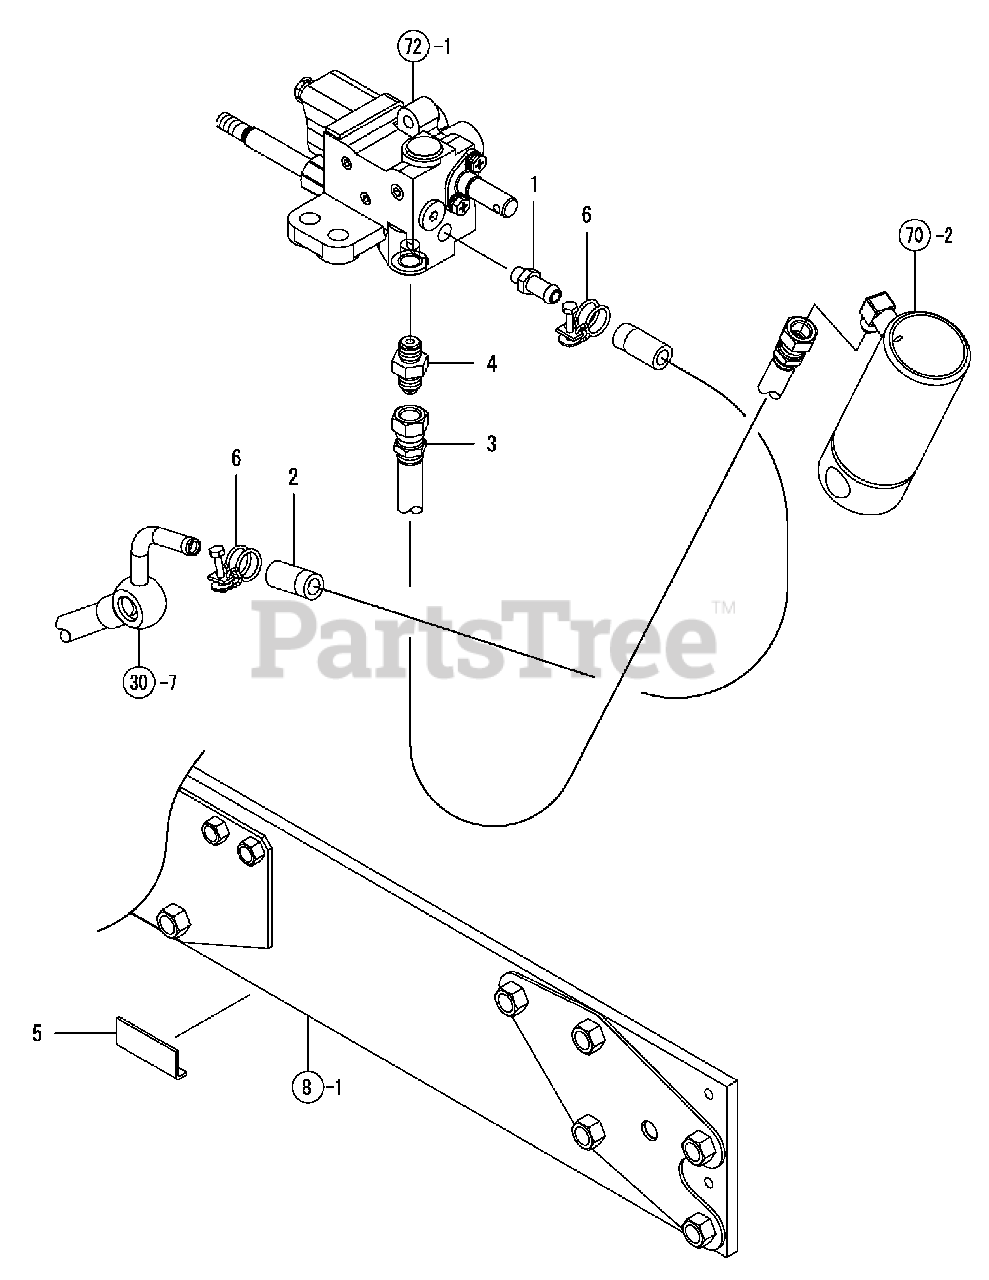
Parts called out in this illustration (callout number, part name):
2	LP HOSE, DRAIN
3	HP HOSE, CLYNDER
4	CONNECTOR PF1/4
